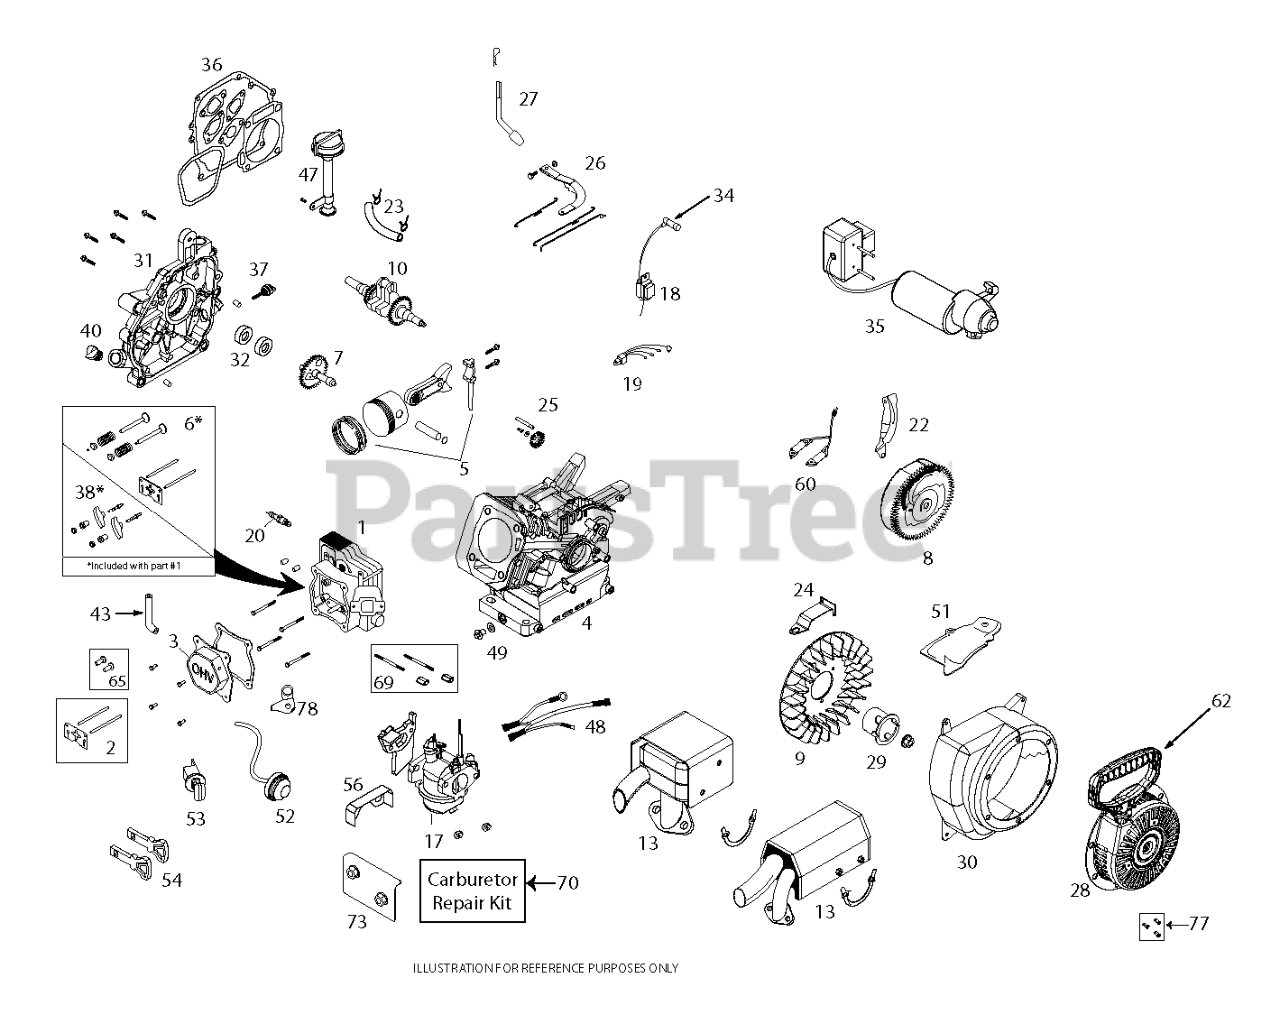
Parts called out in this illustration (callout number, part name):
1	CYLINDR.HEAD.SRV.KIT W/GASKET
2	KIT.PUSH.ROD.SRV(SK208-1001)
3	VALVE COVER ASSEMBLY
4	CYLINDER.ASM.SKSN0001.2
5	KIT.PISTON.SRV(SK208-1400)
6	KIT.CONNECT.ROD.SRV(SK208-1500
7	KIT.CAMSHAFT.208CC.LCT
8	FLYWHL.ASSY.ELECT.(SKSN0405)
9	FLYWHEEL FAN 420586
10	CRNKSHFT-KYD#14.208CCSKSNO8001
13	MUFFLER.ASM.LCT.208CC.SNGL.STG
17	CARB.ASM.SS/SNO.LCT(SKSNO313)
18	IGNITION COIL LCT.SKSN0418.1
19	STARTER.GRIP.SNOW.LCT.SKSN0603
20	SPARK.PLUG(2083810)
22	SHLD.ELEC.START.FLY(SKSN-0605)
23	KIT.FUEL.HOSE.208CC.SING/STAGE
24	SPEED.CTRL.BRKT.(SKSN0150)
25	GOVENOR.GEARS ASM(SK2082900)
26	RP_IT.GOVERNOR.ARM(SUMMER ENG)
27	KIT.GOVERNOR.CRANK(SK208-3100)
28	RECOIL.STRT.ROUND(BLK) SNOW
29	STRTER.CUP(NON-SLOT)SKSN0601.2
30	BLOWER.HOUSING.ELEC.START.LCT
31	COVER CRANKCASE.LCT.SK2083605
31	CRANKCASE COVER ASSY
32	SEAL KIT (2 PCS)
34	SPARK.PLUG.BOOT.SNW,SKSN4691.1
35	STARTER STARTER.EURO
36	GASKET.KIT.208CC(SK2084300.1)
37	DIPSTICK SMALL
38	ROCKER ARM KIT
40	NON REMOVABLE PLUG
43	TUBE.BREATHER.LCT.208
47	TUBE ASSY HIGH OIL-FILL
47	HIGH OIL-FILL TUBE ASSY
48	WIRING HARNESS LCT.SKSN0162.1
49	KIT.OIL.DRAIN.PLUG(SK2089911
51	SHIELD.CYLINGER.LCT.SKSN0608.1
52	BULB.FUEL.PRMR.W/HOSE(SKSNO306
53	SWITH.KEY.ASSEM.SNOW.SINGLE.ST
54	KIT.SNOW.KEY SET2 GRY.HOP.LOGO
56	SHIELD.VAPOR.SNOW
60	CHARGING.COILS.18-WATT
62	HANDLE.RECOIL.DELUXE.LCT
65	TAPPET.KIT.LCT.208CC
69	CARB.STUDS & COUPLING KIT.SNOW
70	CARB.REPAIR.KIT.LCT.SK9900.2
73	SHIELD.INTAKE.(LCT.SKSN0140.1)
77	BOLT.KIT.RECOIL.LCT.ALL.ENGINE
